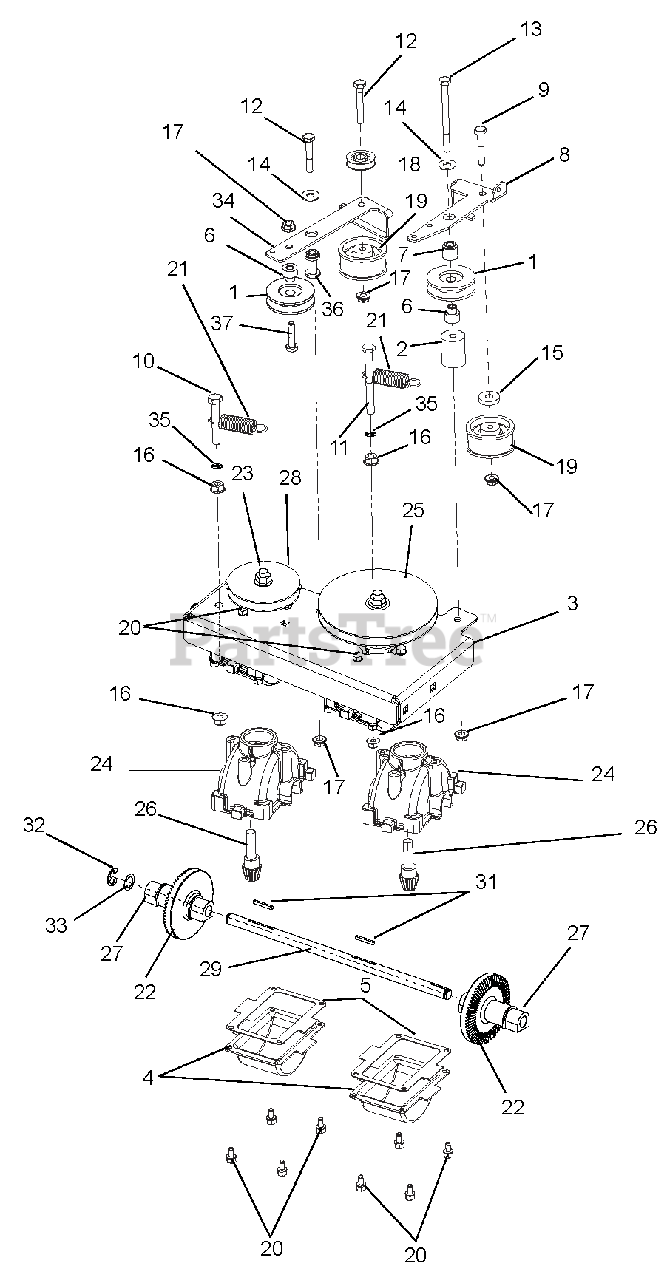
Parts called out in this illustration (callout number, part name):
1	IDLER, 3L FRONT SIDE .38X1.875
2	SPACER, REVERSE IDLER
3	PLATE, TRANSMISSION MOUNT
4	SUMP, GEARBOX
5	GASKET, TRANSMISSION
6	SPACER, V-IDLER PULLEY
7	SPACER, IDLER ARM
8	BRKT-TRANS IDLER ARM
9	@BLT-HEX .25-20X1.50 GR5 YWZC
10	@BLT-HEX .31-18X2.50 GR5 YWZC
11	@BLT-HEX .31-18X3.50 GR5 YWZC
12	@BLT-HEX .25-20X1.75 GR5 YWZC
13	@BLT-HEX .25-20X3.25 YWZC
14	@WSHR-FL-STL.312X.734X.065 YWZ
15	WSHR-FL-STL .328X.87X.179 YWZC
16	@NUT-SPNLK-FLG .312-18 YWZC
17	@NUT-LK-TOP-FLG .25-20 YWZC
18	PULLEY, CABLE
19	PULLEY, ILDER .25X1.875X.97
20	SCR-TAP 10-24X.375 PRE-COAT 80
21	SPRG, TENSION .063X.625X2.50
22	GEAR, BEVEL (CU INFL, KEYWAY)
23	@NUT-LK-TOP-FLG .38-16 YWZC
24	HOUSING, WBLM GEAR BOX
25	PULLEY, WAW REVERSE INPUT
26	PINION, GEARBOX INPUT
27	BUSHING, TRANS OUTPUT SHAFT
28	PULLEY, WAW INPUT
29	SHAFT-TRANS OUTPUT
30	KIT, WAW TRANSMISSION SHAFT
31	KEY, 1/8 X 1/8 X 1.0
32	RG-RTNG-EXT .500X.042 (E)
33	WASHER, .500X.750X.020 THRUST
34	ARM, DOUBLE ACTING IDLER
35	NUT-PUSH .312
36	PIVOT, IDLER
37	@BLT-HEX .25-20X1.25 GR5 YWZC
